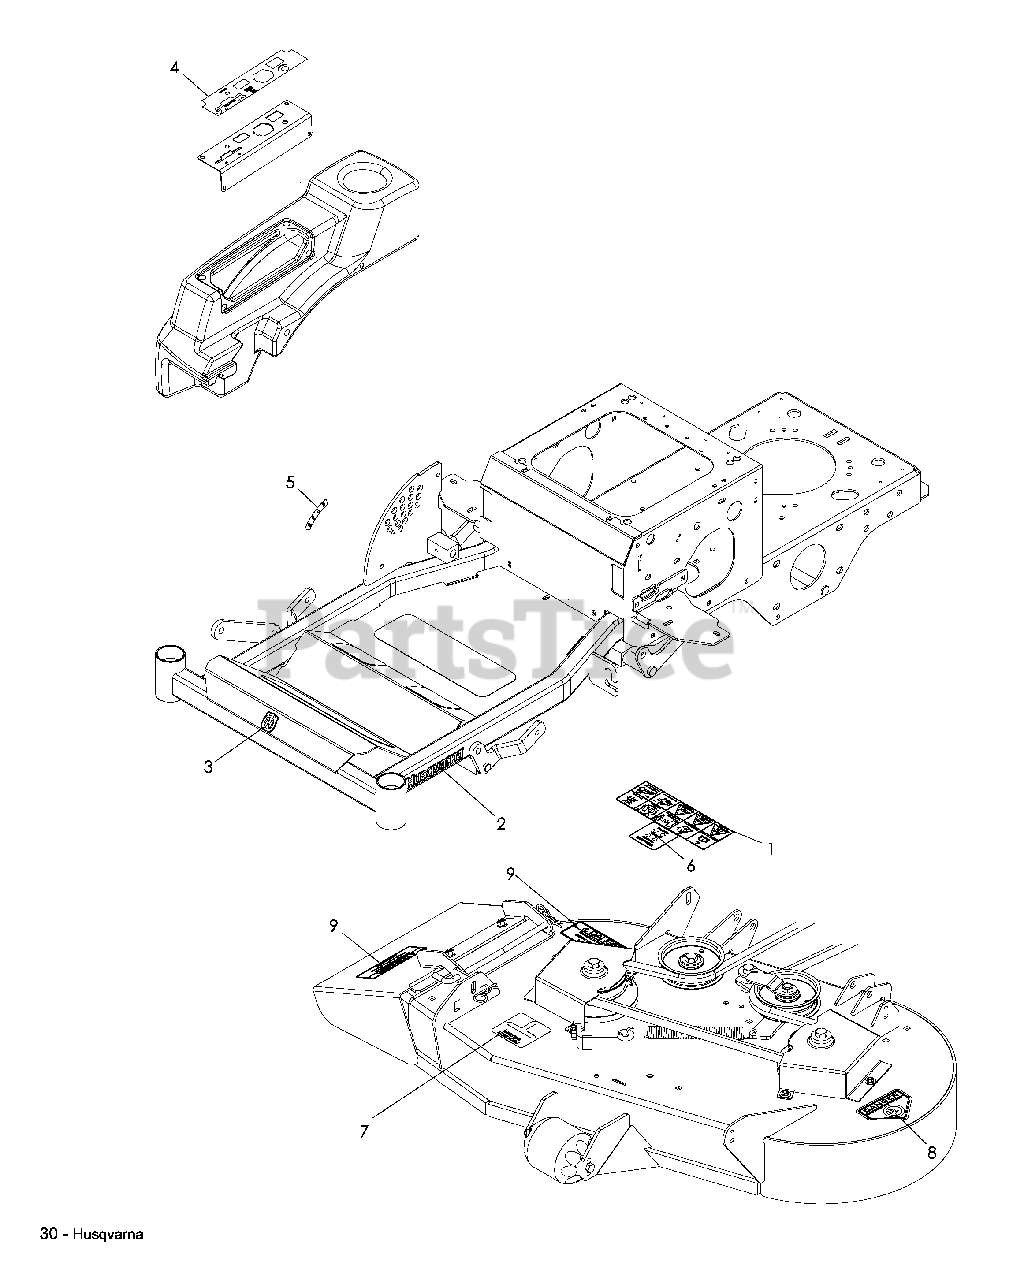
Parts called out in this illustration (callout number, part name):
1	DECAL, OPERATION
2	DECAL, HUSQVARNA
3	DECAL, CROWN
4	DECAL, CONTROL PANEL
5	DECAL, CUT HEIGHT
6	DECAL, LEVER
7	DECAL, BELT ROUTING
8	DECAL, DANGER
9	DECAL, DANGER
